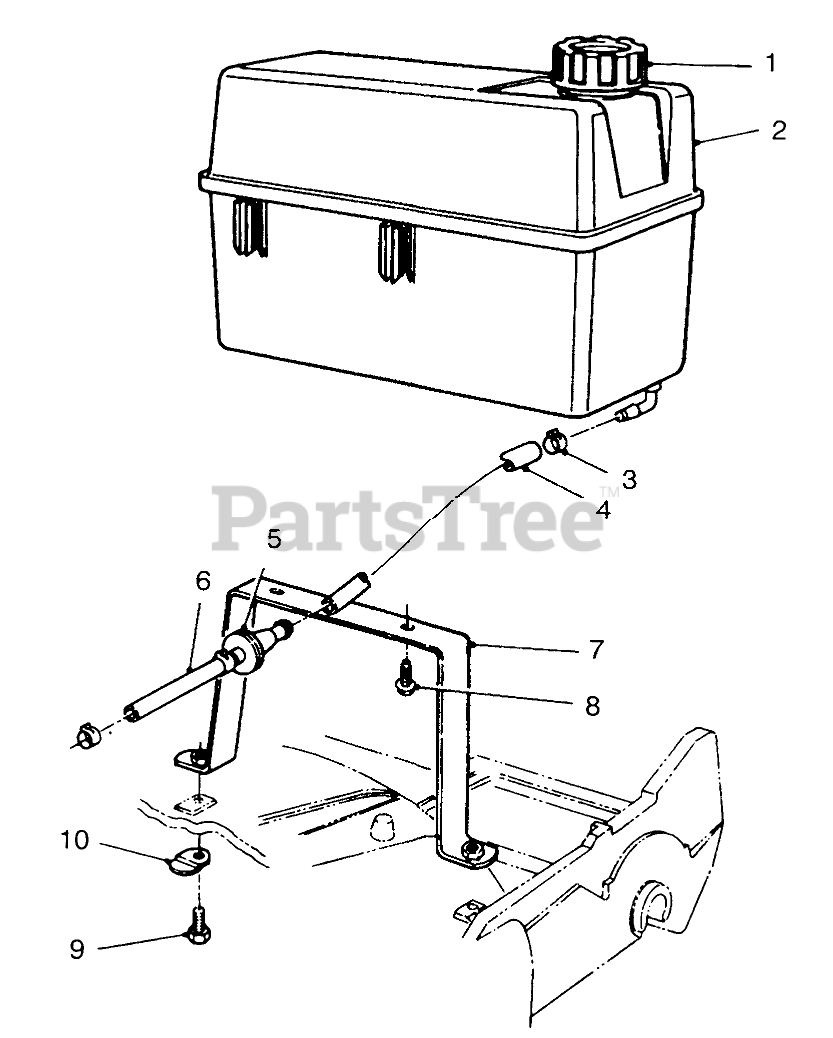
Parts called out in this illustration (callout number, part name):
1	CAP-GAS
2	Tank-Gas
3	CLAMP-FUEL LINE
4	HOSE-FUEL
5	FILTER-FUEL
6	HOSE-FUEL
7	Wa-Base
8	SCREW-HWH
9	SCREW-HH
10	SHIELD-RETAINER
